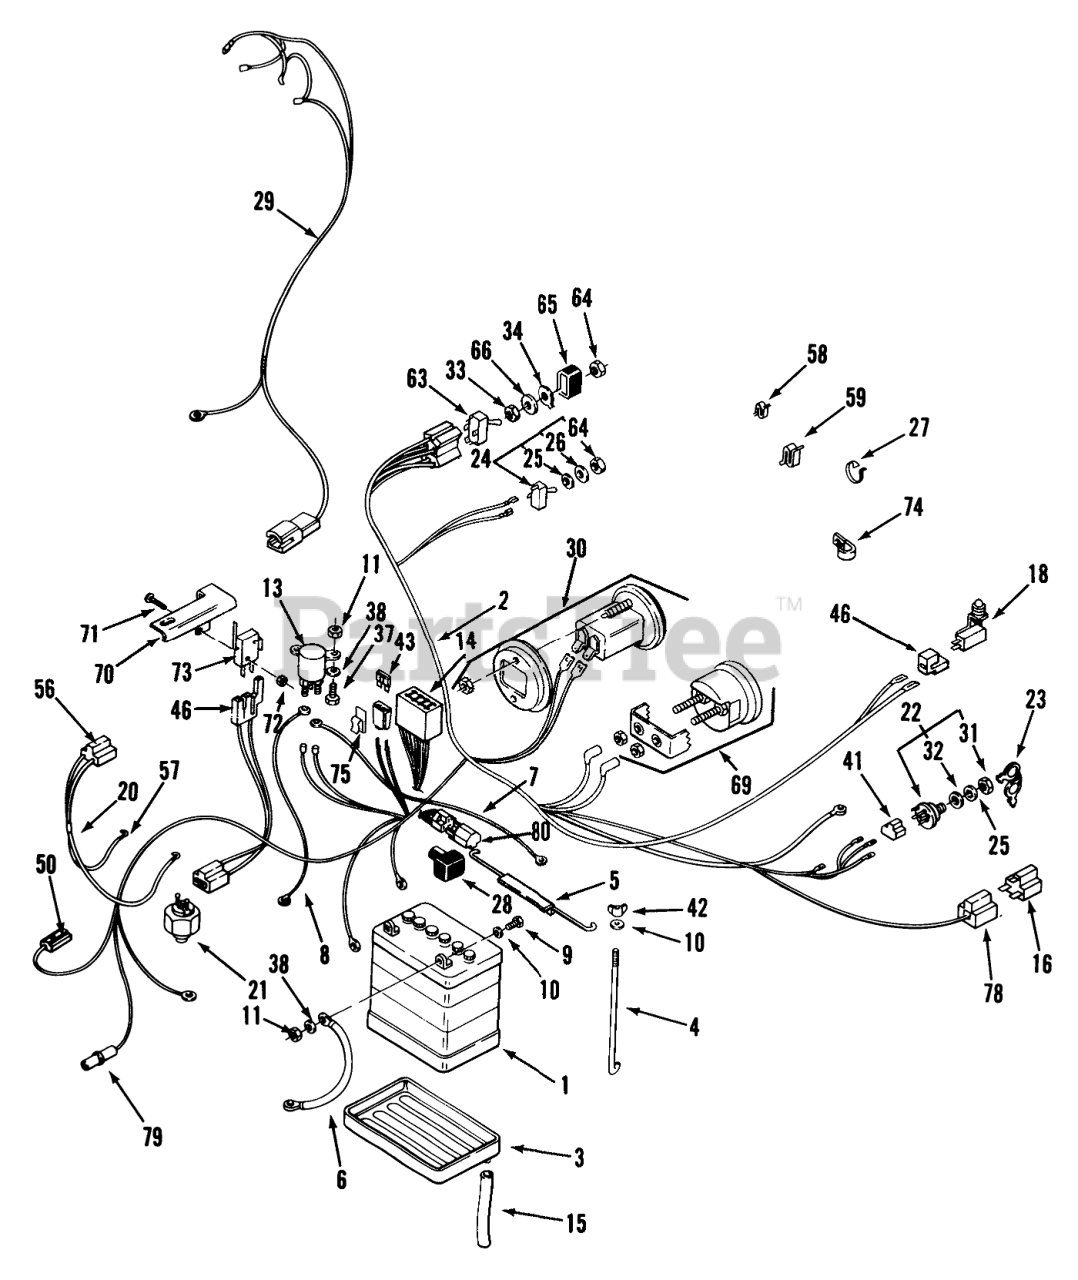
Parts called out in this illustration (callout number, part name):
1	Battery
2	MAIN-HARNESS & DIA
3	TRAY-BATTERY
5	ROD-BATTERY HOLD DWN
6	WIRE -BLACK
7	WIRE - 14" BLACK
8	ASSY WIRE
9	Bolt
11	Nut
13	Solenoid (Includes two of item 11) 210-s
14	FUSE-HOLDER 4 WAY
15	TUBE-BATTERY DRAIN
16	DIODE-ASS'Y
18	Seat Switch
20	ASSY WIRING HARNESS
21	SWITCH (N.C.-TRANS)
22	Ignition Switch (Includes items 31 & 32)
23	Ignition Key
24	Light Switch 212-s (Includes items 33 & 34)
25	Washer
26	Washer
27	PLASTIC TIE
28	Boot
29	HARNESS
30	Hourmeter (Includes 114017 Bracket, 915962 Keps Nut (2) & 5924 E.S. Nut #10-24 (2)
32	LOCKWASHER
33	NUT-HEX, SPECIAL
34	TAB-WASHER
37	Screw
38	Washer
41	CONNECTOR-5 WAY-SERV
42	Nut
43	FUSE-BLADE, 15 AMP
46	CONNECTOR BODY
50	CONNECTOR BODY ELECT
56	CONNECTOR BODY B
57	TERMINAL-TAB RCPT
58	CLIP
59	SPEED CLIP
63	Electric Clutch Switch (Includes items 33, 34 & 64)
65	COVER-PTO SWITCH
66	WASHER
69	Voltmeter (Includes 109650 Clamp & 5924 #10-32 Nut (2)
70	PLATE-TRANS NEUT R
71	Screw
72	NUT HEX 4-40 ELAST
73	SWITCH
74	CLAMP
78	CONNECTOR 5 WAY
79	Connector-Socket
80	RELAY
